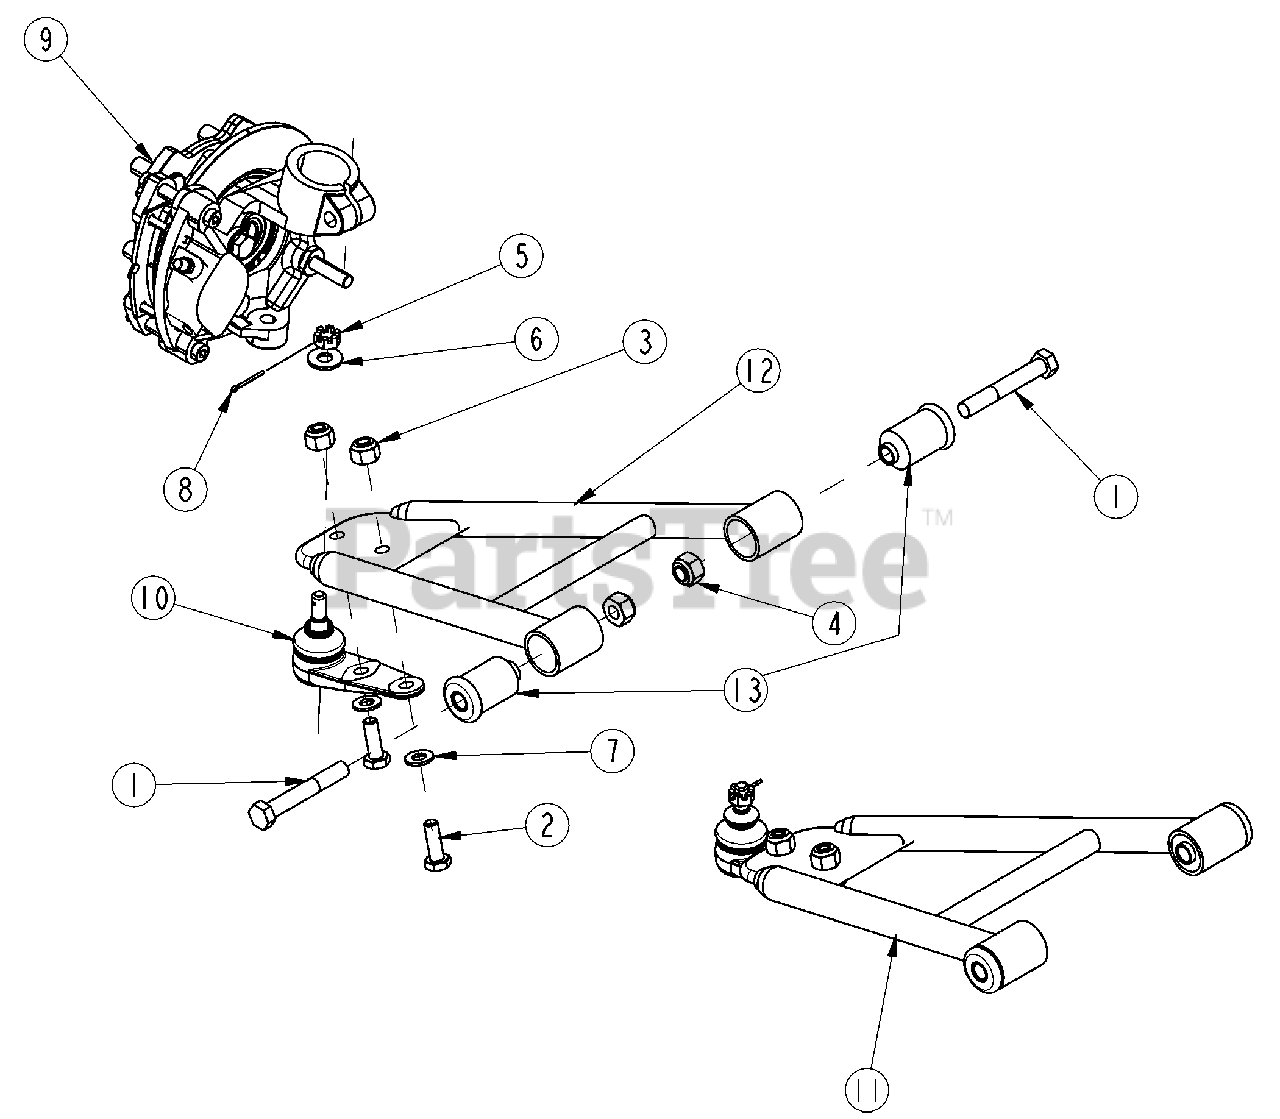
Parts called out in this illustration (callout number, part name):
1	HHCS M12X1.75X80 GR8.8 PLT
2	HHCS M10X1.5X30 GR8.8
3	NUT HEX NYLOCK M10X1.5 PLT
4	NUT HEX NYLOCK M12X1.75 PLT
5	NUT HEX SLOTTED M10X1.25 PLT
6	WASHER FLAT 3/8 USS PLT
7	WASHER, FLAT STEEL .438 x 1.00 x .083
8	PIN COTTER 3/32 X 1 LONG
9	RH DISC BRAKE ASM 172mm W/JNT
9	LH DISC BRAKE ASM 172mm W/JNT
10	BALL JOINT BOLT ON SIR
11	CONTROL ARM ASSEMBLY, LH Includes No. 2, 3, 5, 6, 7, 8, 10, 11, 12 & 13
11	CONTROL ARM ASSEMBLY, RH Includes No. 2, 3, 5, 6, 7, 8, 10, 11, 12 & 13
12	CONTROL ARM WELDMENT, LH
13	CONTROL ARM WELDMENT, RH
